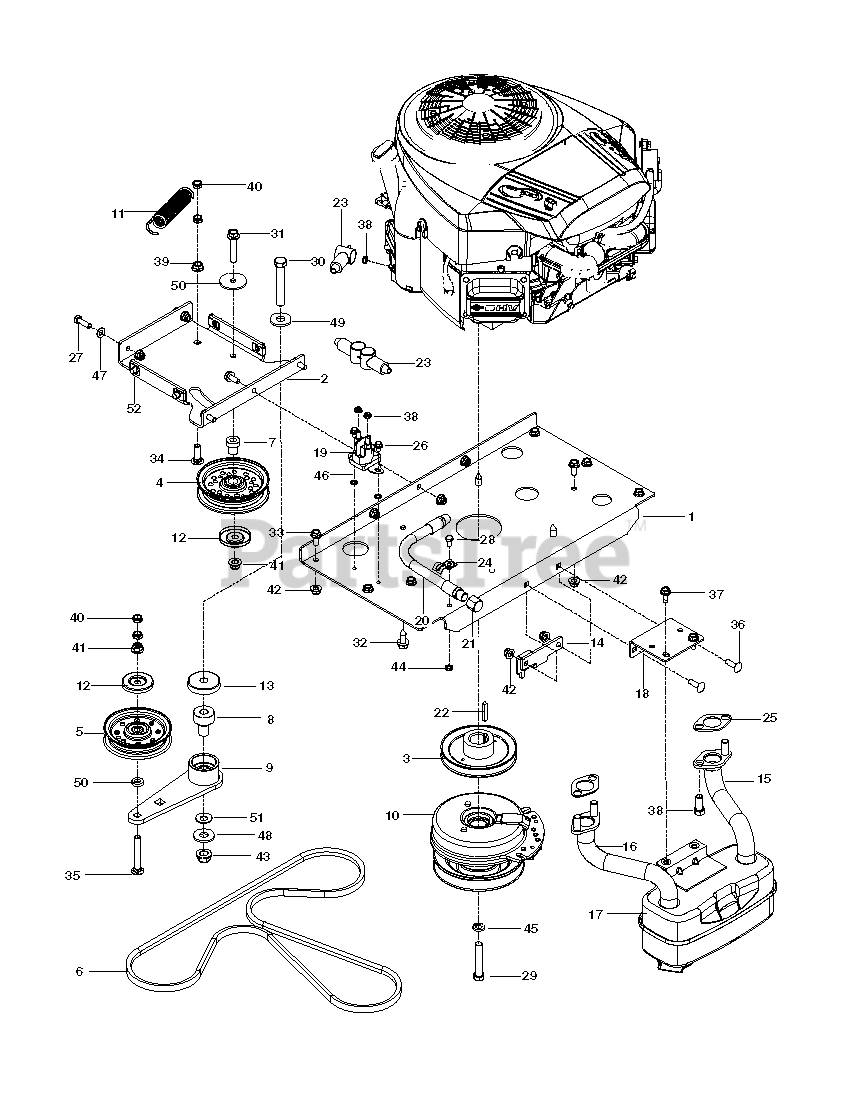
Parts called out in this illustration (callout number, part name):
1	PLATE, ENGINE W/DECALS
2	PLATE, IDLER, BLK
3	PULLEY, V, 1.125 BORE
4	IDLER PULLEY
5	FLAT IDLER PULLEY
6	BELT, HYDRO, 3400
7	PIVOT, IDLER
8	PIVOT, BEARING
9	ARM, IDLER, STEEL, W/BGS
10	CLUTCH 200 FT LB
11	SPRING, PUMP
12	DUST SHIELD
13	SHIELD, DUST
14	STOP, CLUTCH, BLACK
15	RP.EXHAUST.TUBE.LH.BS/TWIN
16	EXHAUST.TUBE.RH.BS/TWIN
17	MUFFLER ASM TWIN
18	BRKT, MUFFLER, BLK
20	OIL DRAIN HOSE
22	KEY, 1/4 SQ X 1 1/4
25	SPRING.BYPASS.CRD
26	HWST 1/4C X 3/8
27	HCS 5/16C X 1
28	HCS 1/4-20.
29	BOLT 7/16F X 2 1/2
30	HCS 1/2C X 3 1/4
31	HHFS 3/8-16 X 2.0 GD 5
32	HHFS 3/8-16 X 1.0 THD FORMING
33	HHFS 5/16-18 X 3/4
34	RHSNB 3/8-16 X 1-1/4
35	RHSNB 3/8-16 X 2.75
36	RHSSNB 5/16C X 1.0
37	BOLT 5/16-18 X 3/4
38	SCREW.SOCKET.HEAD.5/16-18
39	JAM NUT 1/4C (2 2 PW01)
40	NUT HEX 3/8-16 NYLON, THIN
41	NUT 3/8-16 HEX FLG NYLOC ZD
42	5/16-18 NYLOC FLANGE NUT
43	NUT, 1/2-13 HEX FLG NYLOC ZD
44	NUT 3/8C WHIZ
45	WASHER 7/16 LOCK
46	WASHER 1/4 INT TOOTH
47	FLAT WASHER 5/16 SAE
48	WASH USS FLAT 1/2
49	WASHER 3/8 X 3/4 X .187 TK
50	WASHER, 3/8 SPEC
51	CONTACT BELLSPR 1/2
52	U-CLIP 5/16-18 NUT RETAINER
